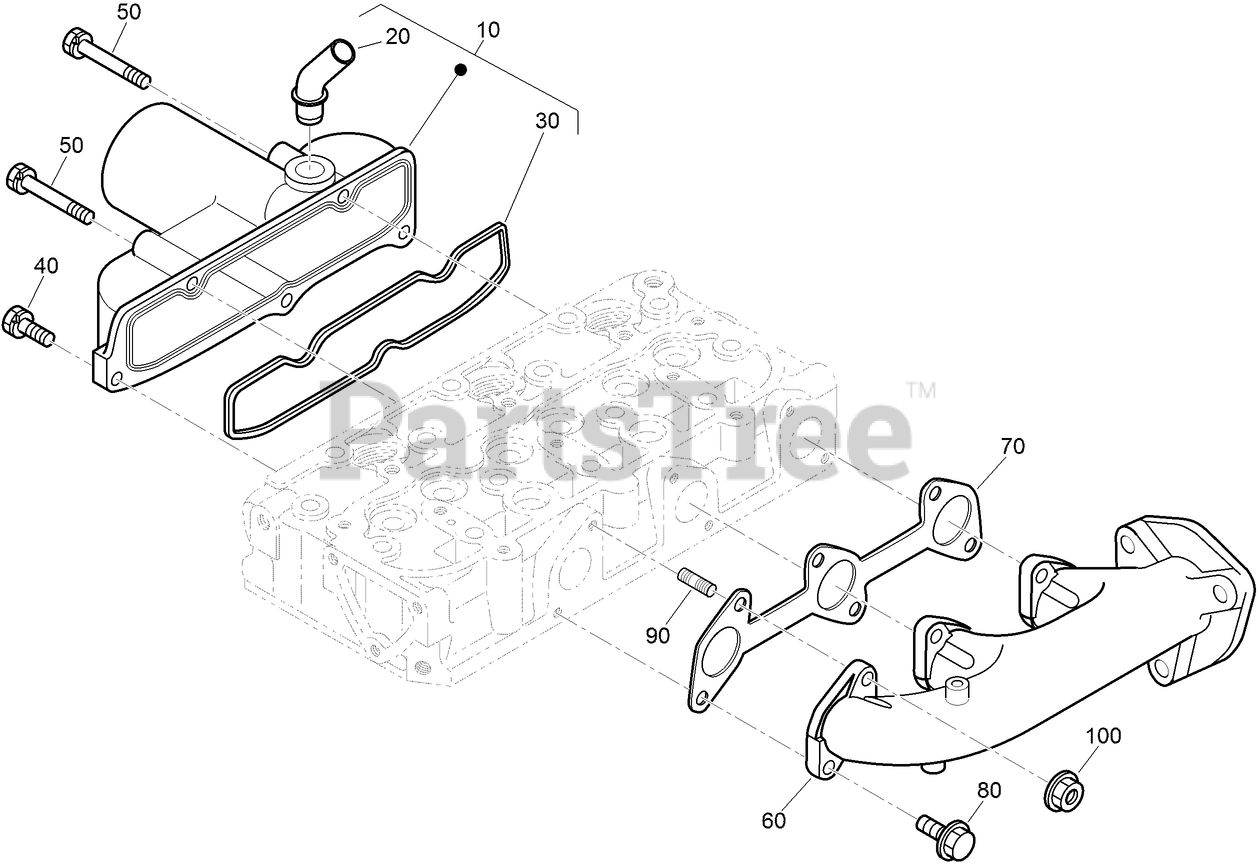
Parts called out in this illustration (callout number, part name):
10	INTAKE MANIFOLD ASM
20	PIPE-BREATHER
30	GASKET-MANIFOLD, INTAKE
40	BOLT-FLANGE
60	MANIFOLD-EXHAUST
70	GASKET-MANIFOLD, EXHAUST
80	OBS BOLT-UBS
90	BOLT-STUD
